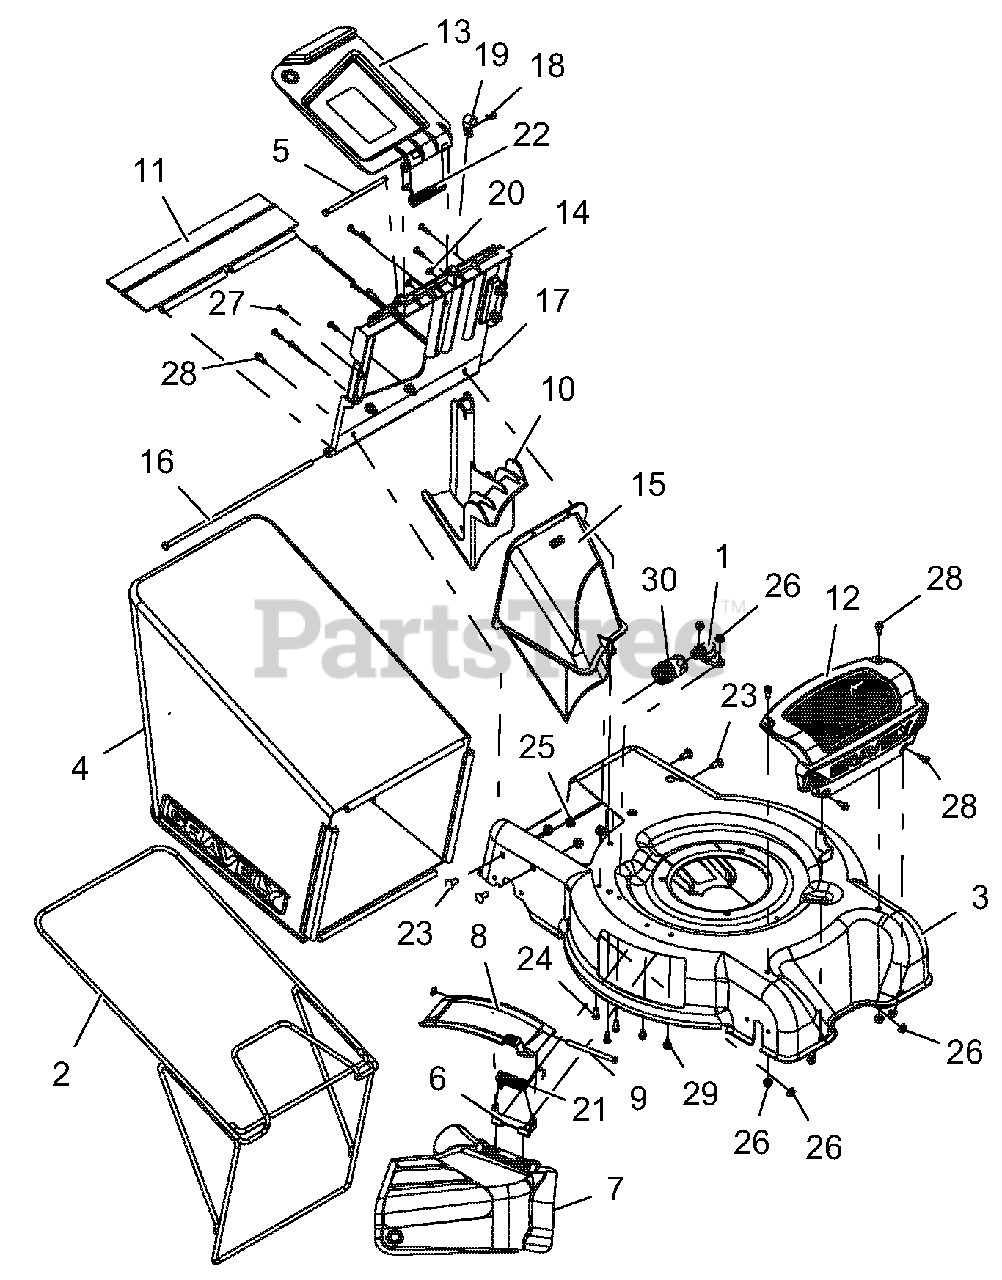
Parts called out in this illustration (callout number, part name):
1	ASM, WASHOUT PORT W/ O-RING
2	FRAME, BAGGER
3	DECK, XD3 W/ SAFETY DECALS
4	BAGGER, GRASS GRAVELY
5	PIN, 5/16 X 5.50
6	BRKT, HINGE LM
7	CHUTE, SIDE DISCHARGE - LM
8	COVER, SIDE DISCHARGE - LM
9	PIN, SIDE DISCHARGE
10	PLUG, MULCH
11	GUARD, REAR
12	TRIM, FRONT
13	DOOR, REAR
14	HANGER, BAG
15	CHUTE, REAR DISCHARGE
16	ROD, REAR GUARD
17	NUT, PUSH .312
18	PIN, HAIR INT .08X.18X1.18 YWZC
19	CLAMP, LM CABLE
20	PLUG, 5/16 HOLE, .125 MATL PLASTIC
21	SPRG, TORSION
22	SPRG, TORSION
23	BLT-RDHDSQNK .31-18X.75 G5 YWZC
24	BLT-HEX .25-20X.63 GR5 YWZC
25	NUT, LK-TOP-FLG .312-18 YWZC
26	NUT, LK-TOP-FLG .25-20 YWZC
27	SCR-TAP #12-14X.75 PLASTITE BLZC
28	SCR-TAP .25-20X.62 HWH TR YWZ
29	SCR-TAP .25-20X.37 HWH YWZ TR
30	COUPLING, QUICK DISCONNECT
